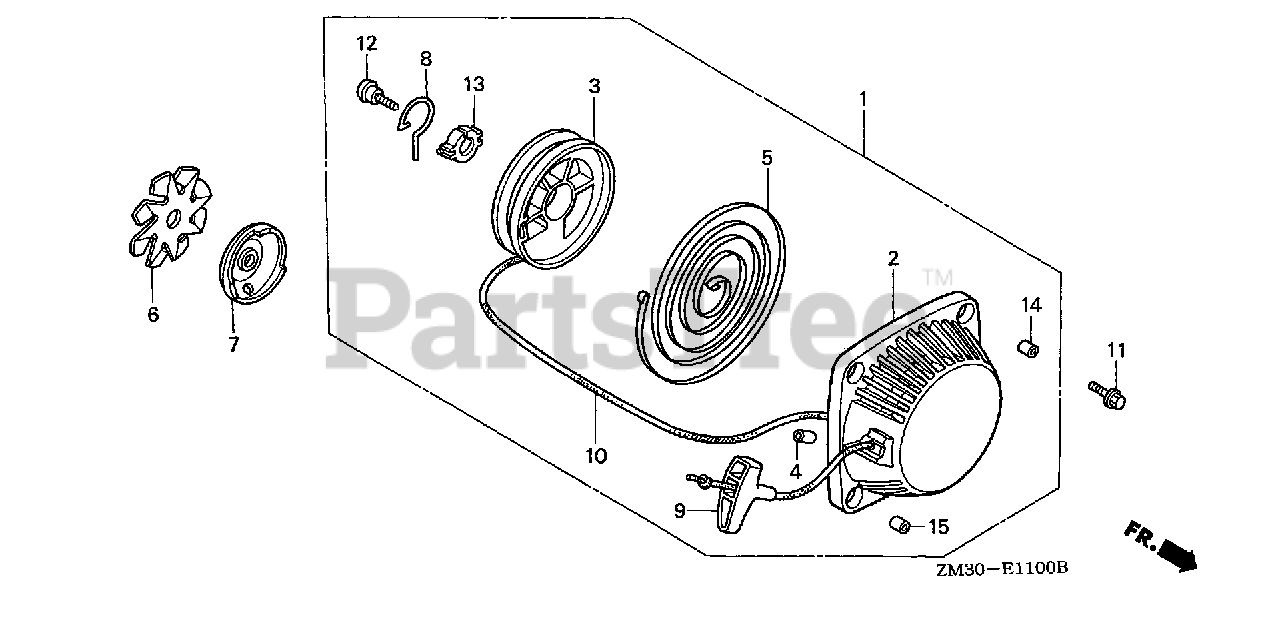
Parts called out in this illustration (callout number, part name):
1	STARTER ASSY., RECOIL *NH1* (BLACK)
2	CASE, RECOIL STARTER
3	REEL, RECOIL STARTER
4	GUIDE, ROPE
5	SPRING, RECOIL STARTER
6	FAN, RATCHET
7	PULLEY, RECOIL STARTER
9	KNOB, RECOIL STARTER
10	ROPE, RECOIL STARTER
11	BOLT, FLANGE (5X18)
12	SCREW, SETTING
